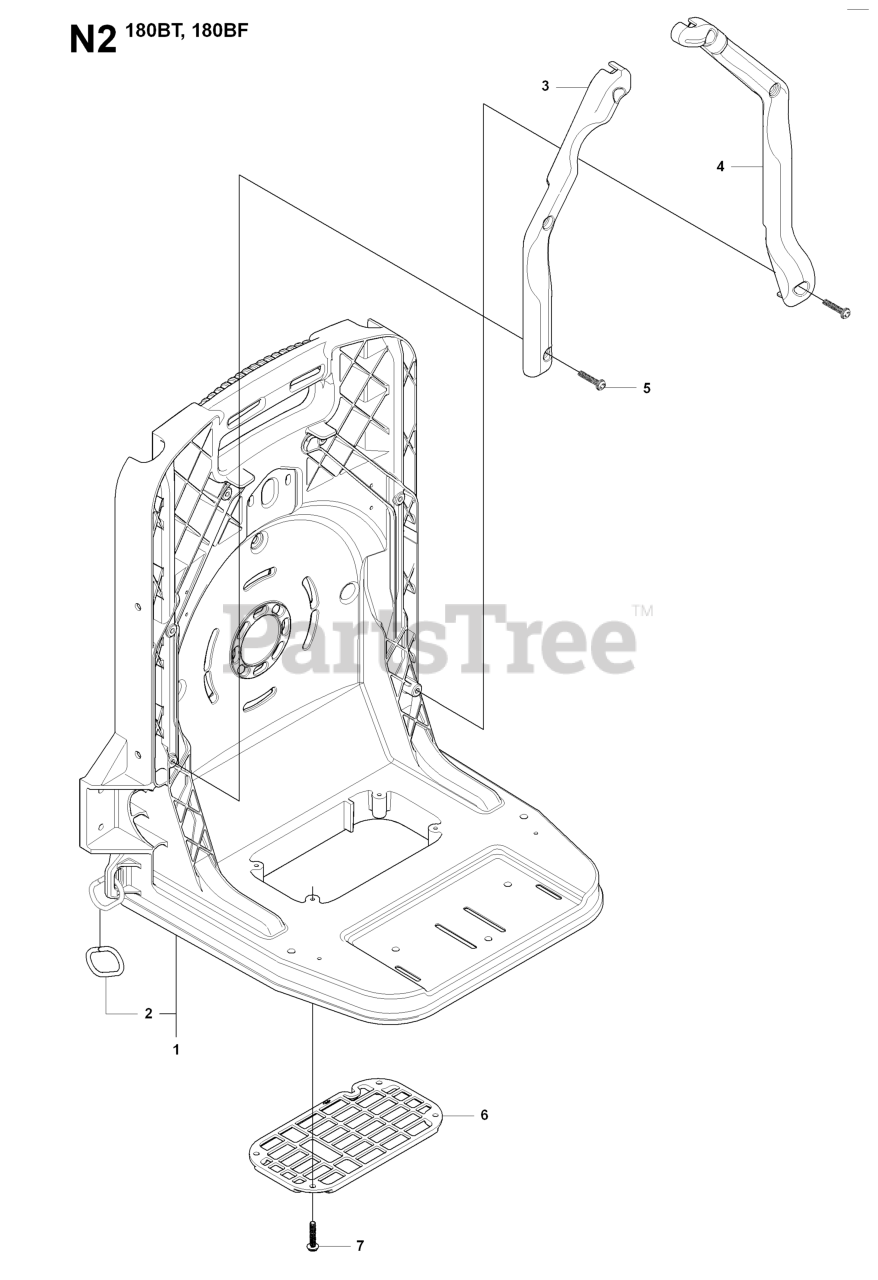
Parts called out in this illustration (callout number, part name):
2	RING
5	SCREW
7	SCREW
